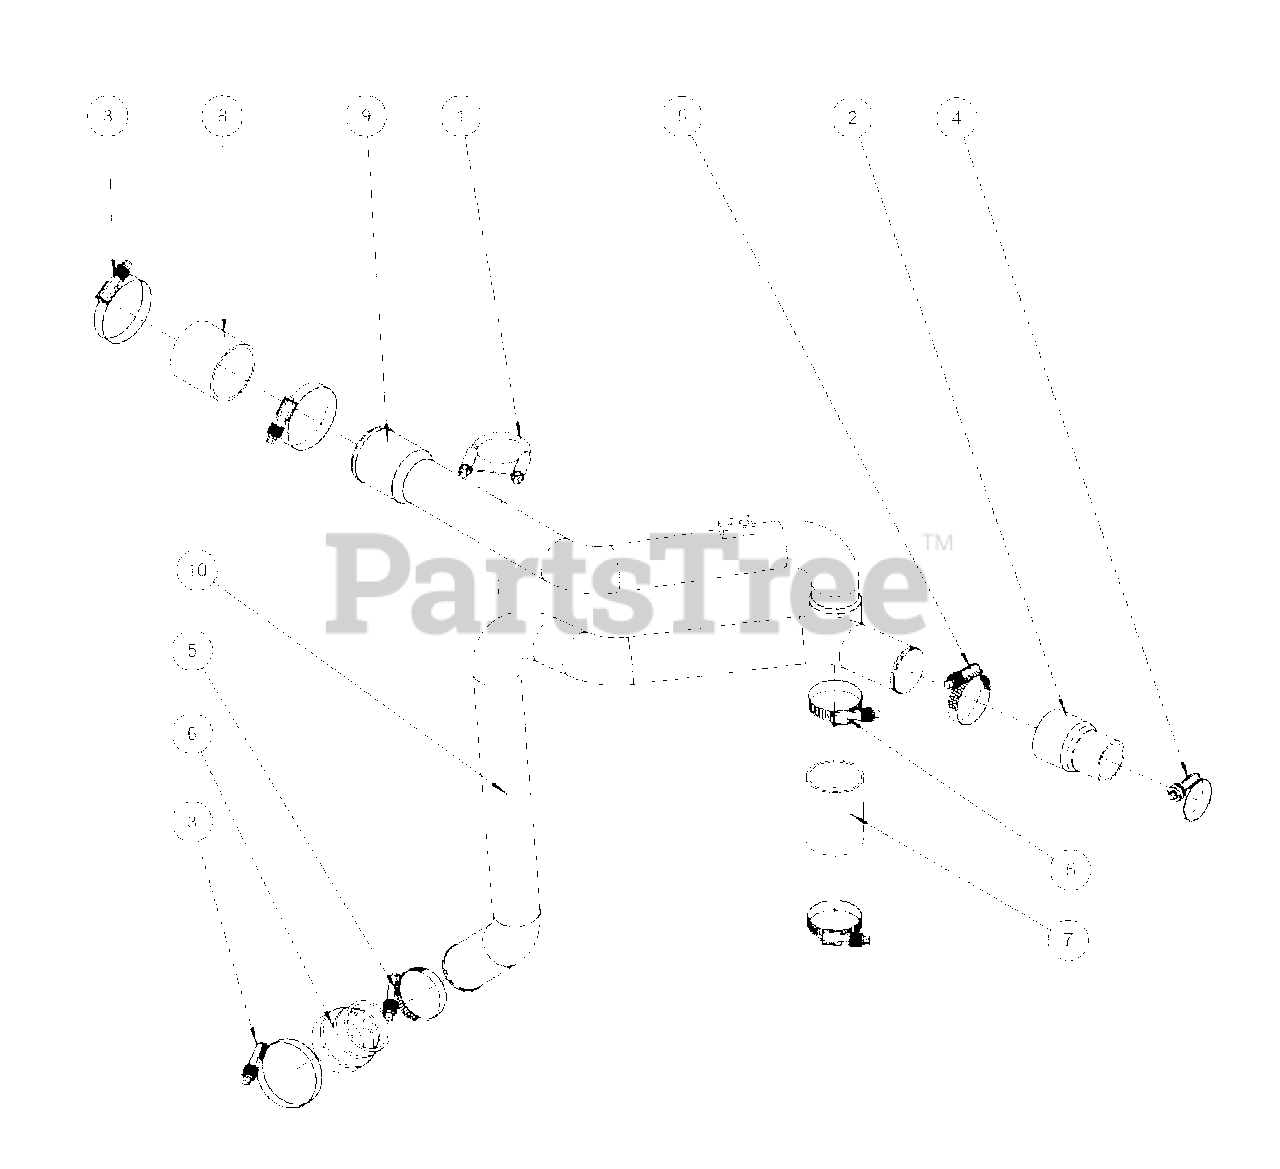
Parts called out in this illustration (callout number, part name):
1	* CLAMP
2	* HOSE
3	* CLAMP
9	* PIPE
10	* PIPE
